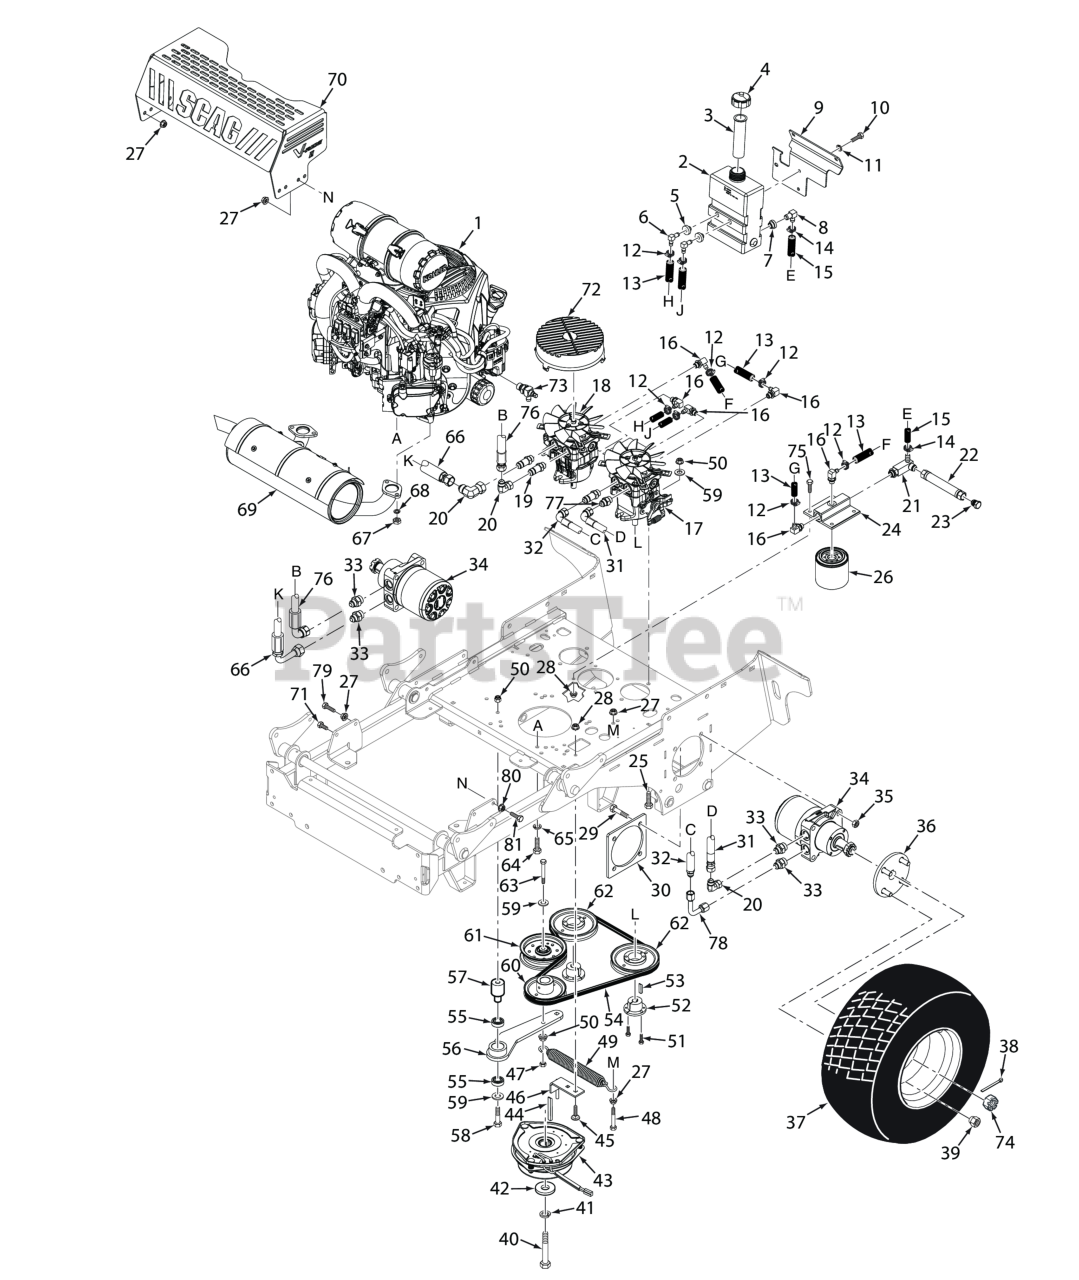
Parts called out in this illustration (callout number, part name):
1	Engine, Kawasaki 26FT-EFI
2	Hydro Tank Assy., SVRII
3	Insert, Filler Neck
4	CAP, HYDRAULIC TANK
5	Bushing, 0.56" Dia. Viton
6	Elbow, 90 Degree, 9/16-18 JIC x 9/16 O-Ring
7	Bushing, 0.78" Dia. Viton
8	Fitting, 90 Degree - 1/2" Hose
9	Bracket, Hydro Tank Mounting
10	BOLT, SERRATED FLANGE HEX HEAD 5/16-18 X 3/4"
11	Lockwasher, 5/16 (.317 x .586 x .078) Helical Spring
12	Clamp, .69" Max. / .25" Min. Dia.
13	Hose, 3/8" ID - 10-1/4" Long (Order By The Inch)
14	Clamp, Cable 3/4" I.D.
15	Hose Assembly, 1/2" ID (Oil Reservoir to Filter Base)
16	Elbow, 90 Degree - 9/16" O-Ring x 3/8" Hose
17	Pump, LH - SVRII
18	Pump, RH - SVRII
19	Union, O-Ring to JIC
20	Elbow, 1/2 JIC Female to 1/2 JIC Male
21	Tee, 3/4" O-Ring
22	Drain, Hose Assembly
23	Plug, JIC 3/4-16 UNF
24	Filter Head Assembly
25	Bolt, Hex Head, 3/8-16 x 1-1/2"
26	OIL FILTER, SPECIAL
27	NUT, 3/8-16 SERRATED FLANGE HEX HEAD
28	Nut, Serrated Flange 5/16-18 (Right Front Engine Mounting, Briggs and Kohler Only)
29	Bolt, Hex Hd. 1/2-13 x 2-1/2" (lower)
30	Plate Weldment, Motor Backing
31	Hose Assembly
32	Hose Assy., 18-1/2"
33	TUBE UNION, 3/4-16 JIC TO 7/8-14 "O" RING
34	Wheel Motor, Parker
35	Locknut, Hex 1/2-13 Center Lock
36	Wheel Hub Assy., SVRII
37	Wheel Assy., 24 x 9.5 - 12 (4-Ply) (48 / 52)
38	Pin, Cotter 9/16" x 1-1/2"
39	Wheel Nut, 1/2-20 x 13/16
40	Bolt, Hex Head 7/16-20 x 2-1/4" w/Patch (Kawasaki)
41	Lockwasher, 7/16� Spring
42	Flatwasher, 7/16-.469 x 1.75 x .25 (48, 52)
43	Clutch w/Tag GT2.5-FE02 (48 / 52)
44	Key, 1/4 x 1/4 x 3-1/2"
45	Bolt, 5/16-18 x .75 RHSN Carriage
46	ANTI-ROTATION WLMT, SVRII
47	Bolt, Hex Head 3/8-16 x 1" Ser. Flg.
48	Bolt, Hex Head 3/8-16 x 3" - 52"
49	Spring, Transmission Idler
50	HEX NUT, ELASTIC STOP LOCK, 3/8-16
51	Bolt, Hex Head 1/4-20 x 1" Grade 8 Black
52	Hub, Tapered, 15mm Bore
53	KEY, 5 MM X 5 MM X 25 MM
54	Belt, Pump Drive (48 & 52)
55	BEARINGS, BALL, NEUTRAL RETURN
56	Idler Arm Assy.
57	Pivot, Idler
58	Capscrew, Hex Head 3/8-16 x 3.25"
59	Flatwasher, 3/8 (.391 x .938 x .105 HD) Grade 8
60	Pulley, 4-3/4" OD - 1.125 Bore
61	Pulley, Idler 4-1/2"
62	Pulley, 5.45 OD - Tapered Bore"
63	Bolt, Hex Head 3/8-16 x 2-3/4" Full Thread
64	Bolt, Hex Head 3/8-16 x 1-1/4", Kawasaki FX / FS
65	Lockwasher, 3/8" Spring, Kawasaki FX / FS
66	Hose Assy., 15-1/4"
67	Nut, M8 x 1.25 Hex Special
68	Lockwasher, M8 Spring (Kawasaki)
69	Muffler, Kohler CV-EFI - SVRII
69	Muffler, Kawasaki FT26-EFI - SVRII
70	Heatshield, Muffler- SVRII
71	Bolt, Hex Head, 3/8-16 x 3/4"
72	Fan Cover, Pump
73	Oil Drain, M20 Thread (Kawasaki)
74	Nut, Hex Castle 1.0-20 UNEF
75	Bolt, Heax Head 5/16-18 x 1" (48V / 52V)
76	Hose Assy., 27-1/2"
77	Union, 3/4"-16 JIC x 3/4"-16 O-Ring
78	Tube Assy.
79	Bolt, Hex Head 3/8-16 x 1-1/2" Grade 8 Black
80	NUT, 3/8-16 SERRATED FLANGE HEX HEAD
81	Bolt, Hex Head, 3/8-16 x 3/4"
